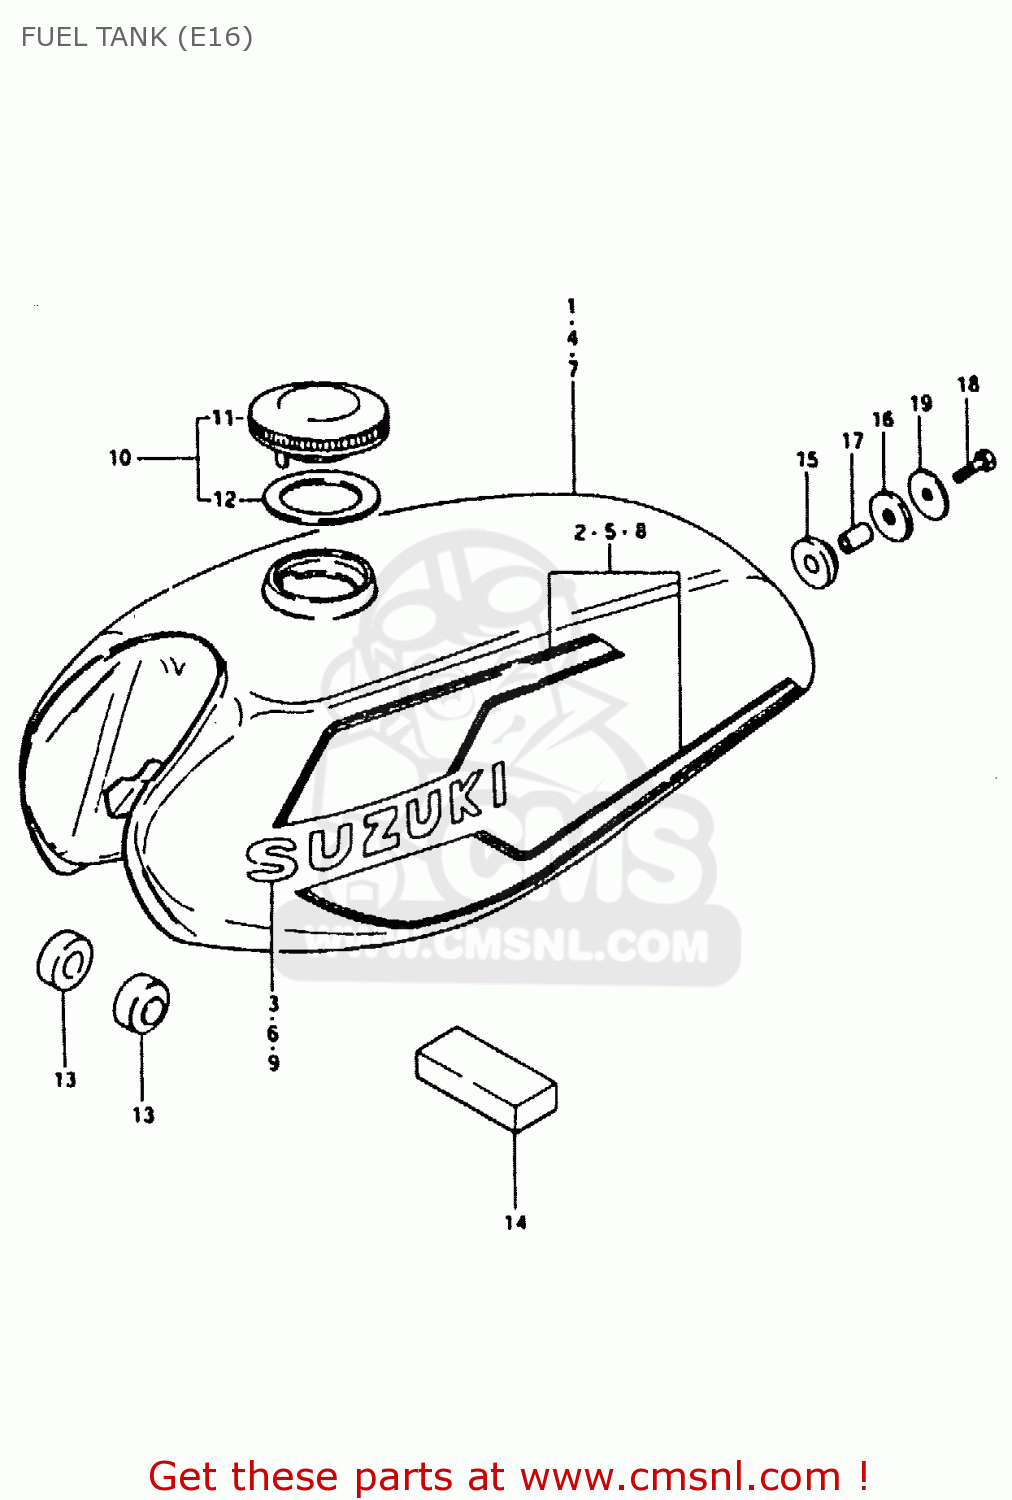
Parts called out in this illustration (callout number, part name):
1	TANK, FUEL (BLUE)
2	TAPE SET
3	EMBLEM (WHITE)
4	TANK, FUEL (RED)
5	TAPE SET
6	EMBLEM (WHITE)
7	TANK, FUEL (WHITE)
8	TAPE SET
9	EMBLEM (BLACK)
10	CAP ASSY,FUEL TANK FILLER
11	CAP,FUEL TANK
12	GASKET (NAS)
13	CUSHION
14	CUSHION
15	CUSHION
16	CUSHION
17	SPACER(8.5X12X19)
18	BOLT (8X30)
19	WASHER (8.5X29X1.6)
